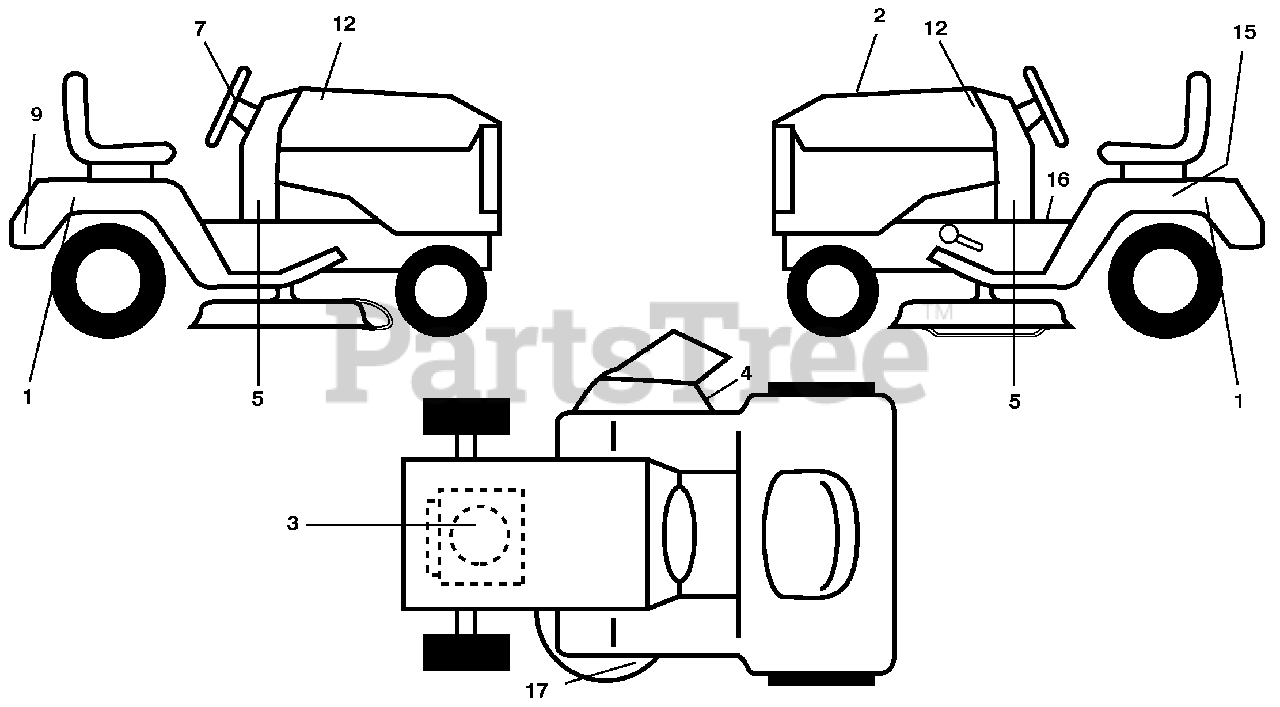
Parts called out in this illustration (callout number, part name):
1	Decal, Fender RH/LH
2	Decal, Replacement
3	Decal, Engine HP
4	Decal, Warning
5	Decal, Lower Dash
7	Decal, Ins Str Wh
9	Decal, Fender
12	Decal, Hood RH/LH
15	Decal, Caution, Battery
16	Decal, Fender Warning Eng/Fr
17	Decal, V-Belt Sch.
17	Decal, Handle Lft Height Adj.
17	Manual, Operator's E&F
17	Manual, Parts E&F
